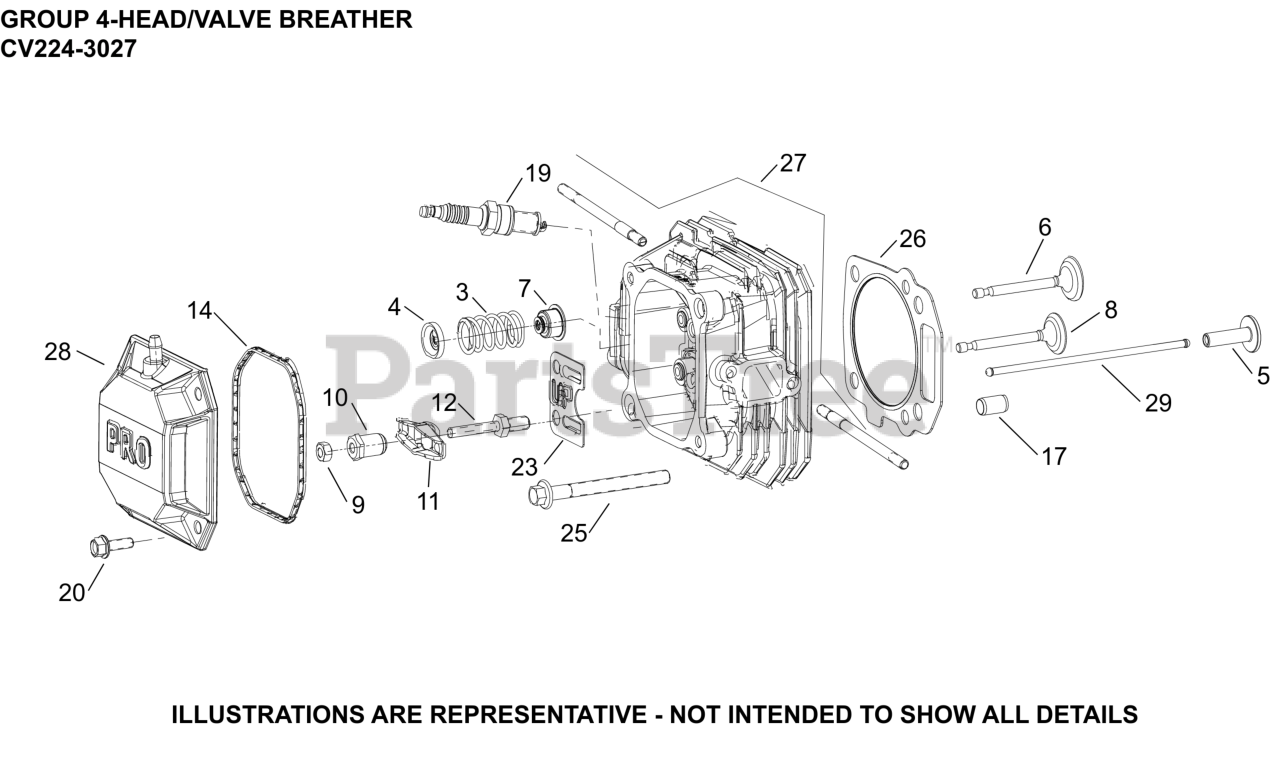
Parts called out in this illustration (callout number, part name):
3	SPRING, VALVE
4	RETAINER, VALVE SPRING
5	LIFTER, VALVE
6	VALVE, INTAKE
7	SEAL, VALVE
8	VALVE, EXHAUST
9	NUT, HEX JAM
10	PIVOT, ROCKER ARM
11	ARM, ROCKER (1.2: 1 RATIO)
12	STUD, ROCKER ARM
14	SEAL, VALVE COVER
17	DOWEL, CYLINDER HEAD
19	PLUG, SPARK 12MM RFI
20	SCREW, HEX FLANGE (M6)
23	PLATE, PUSHROD GUIDE
25	SCREW, HEX FLANGE (M8)
26	KIT, HEAD GASKET
27	KIT, CYLINDER HEAD-USE 14 818 01-S
NI	COVER, VALVE ASSEMBLY
NI	ROD, PUSH
